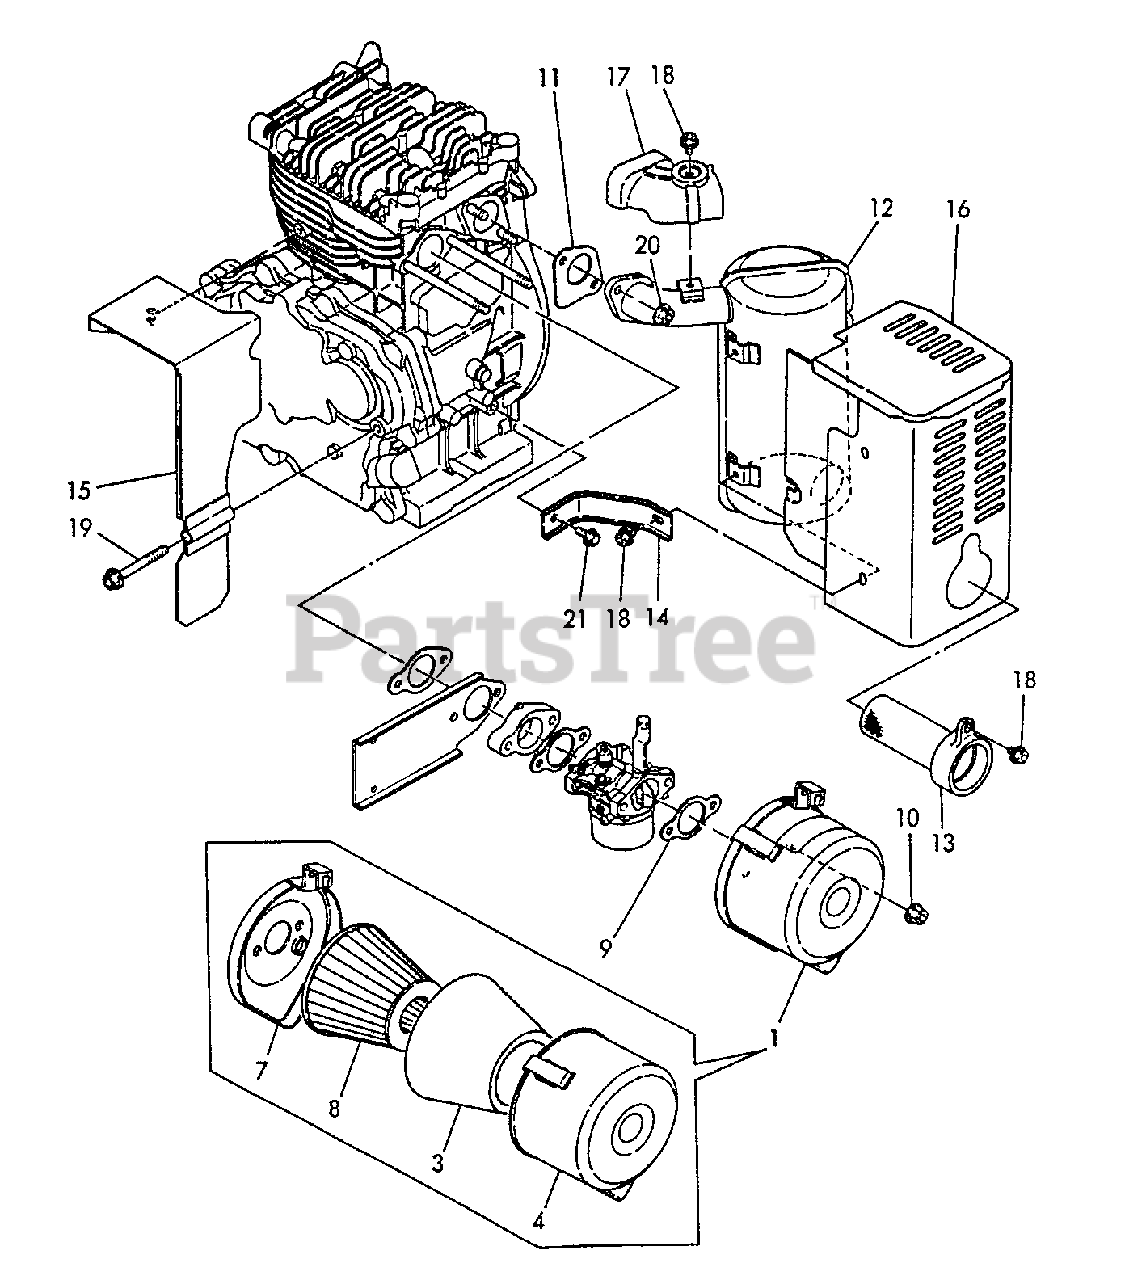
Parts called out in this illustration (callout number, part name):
1	AIR CLEANER ASSY
3	FILTER, AIR
4	BODY ASSY
7	PLATE
8	ELEMENT (2ND)
9	GASKET, INTAKE
10	NUT - 8
11	GASKET, EXHAUST
12	MUFFLER
13	SCREEN, SPARK ARRESTOR
14	STAY, MUFFLER
15	PLATE, GUIDE
16	COVER, MUFFLER
17	COVER-C, MUFFLER
18	BOLT - 6X8 -- PLATED
19	BOLT - 8X60 -- PLATED
20	NUT - 8
21	BOLT - 6X8 -- PLATED
